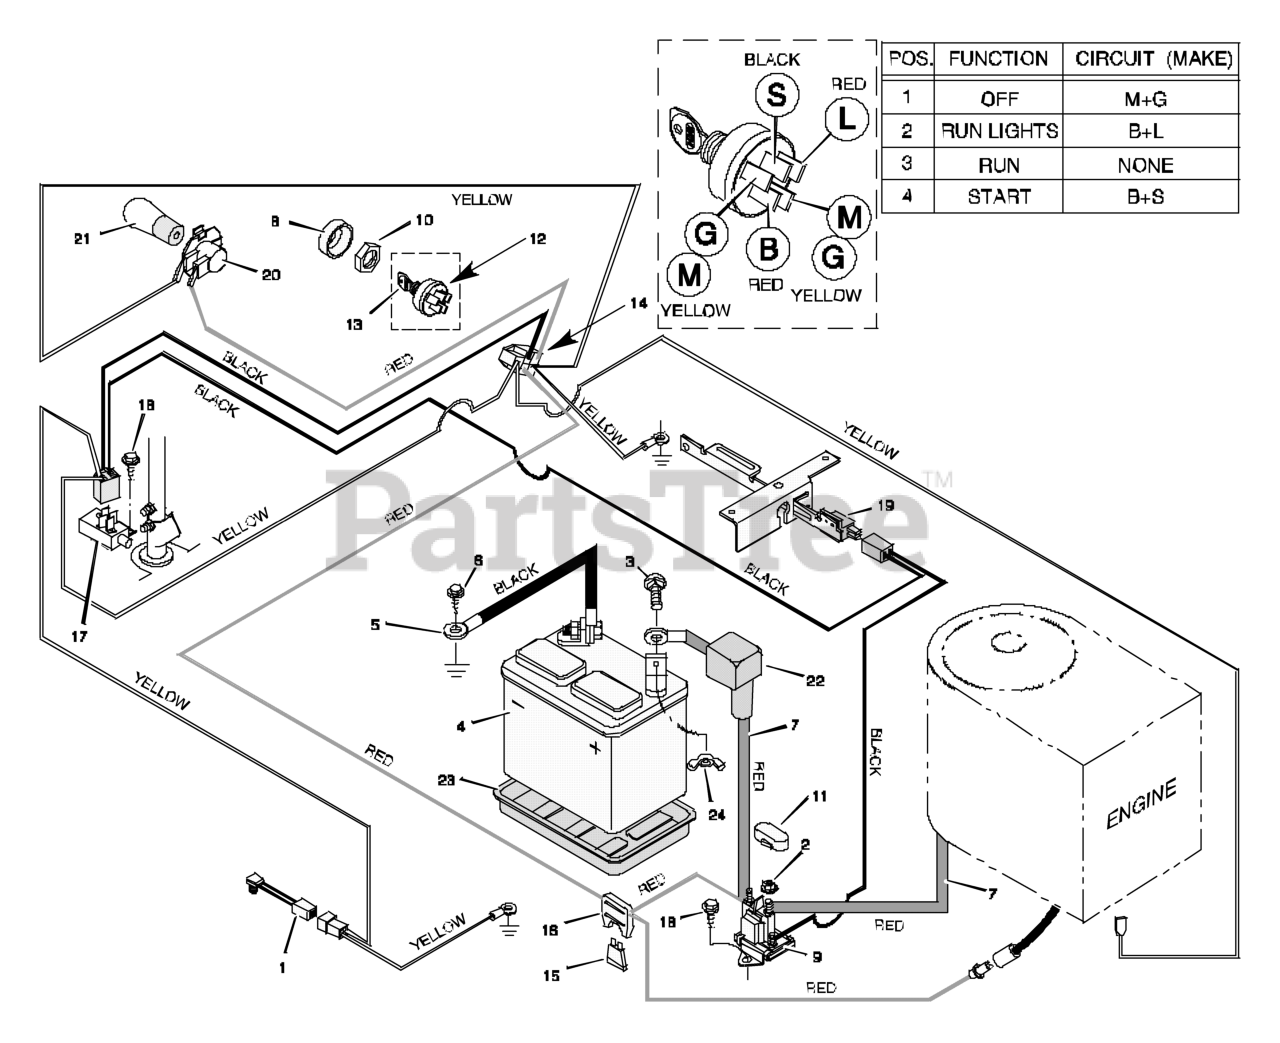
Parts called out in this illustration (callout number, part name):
1	Switch, Seat Sensor
2	Locknut
3	Bolt
4	Battery
5	Cable, Battery Ground
7	Cable, Red Battery
8	Cap, Ignition
9	Solenoid
10	Nut, Hex
11	Cover, Solenoid
12	Switch, Ignition
13	Key, Ignition
14	Harness, Chassis Wire
16	Holder, Fuse
17	Switch, Limit
19	Switch, Limit
20	Socket, Light
21	Bulb, Light
22	Cover, Terminal
23	Tray, Battery
24	Wingnut
